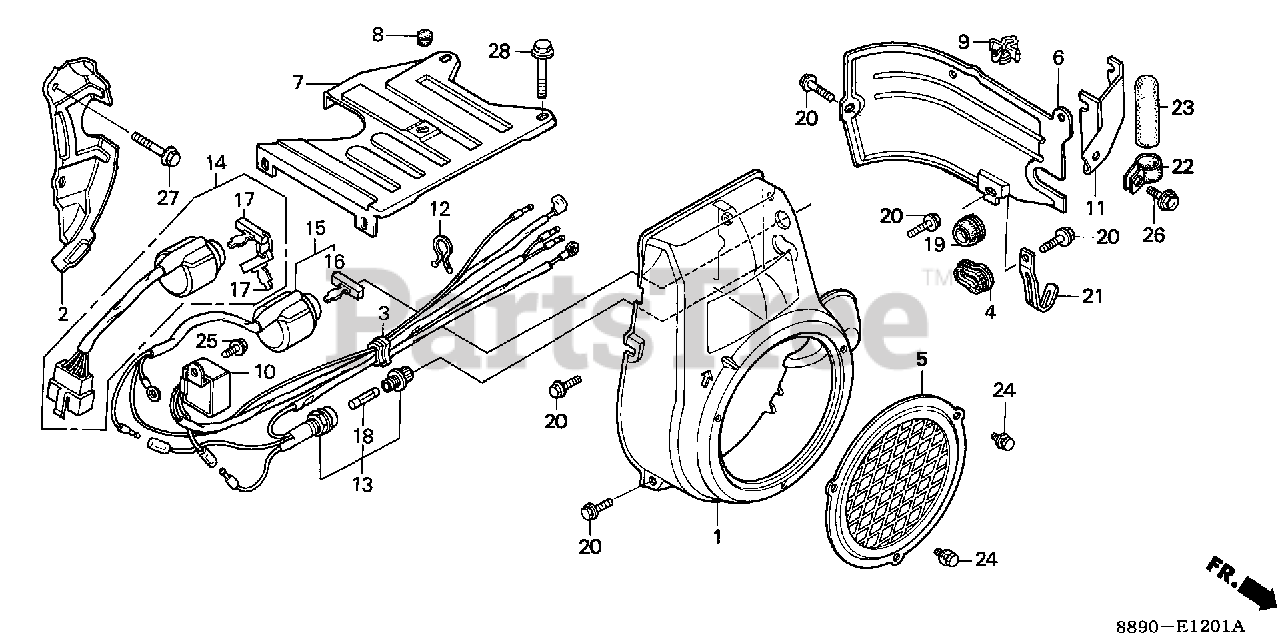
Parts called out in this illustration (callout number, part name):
1	COVER, FAN *R8* (BRIGHT RED)
2	PLATE, SIDE
3	GROMMET, SWITCH CORD
5	PROTECTOR, FAN COVER *R8* (BRIGHT RED)
7	COVER, TOP
8	GROMMET, TOP COVER
9	CLIP, IGNITION WIRE (8MM)
10	RECTIFIER, SILICON (NOT AVAILABLE)
11	STAY, CLAMP
12	CLIP, PURSE LOCK
13	HOLDER, FUSE (1.5A) (NOT AVAILABLE)
14	SWITCH ASSY., COMBINATION
14	SWITCH ASSY., COMBINATION (NOT AVAILABLE)
15	SWITCH ASSY., COMBINATION (NOT AVAILABLE)
17	KEY (HONDALOCK)
18	FUSE (1.5A) (NOT AVAILABLE)
20	BOLT, FLANGE (6X12) (CT200)
22	CLIP, CORD
23	TUBE, CORD (25MM)
24	BOLT, FLANGE (6X8)
25	BOLT, FLANGE (6X10)
26	BOLT, FLANGE (6X12)
27	BOLT, FLANGE (8X20)
